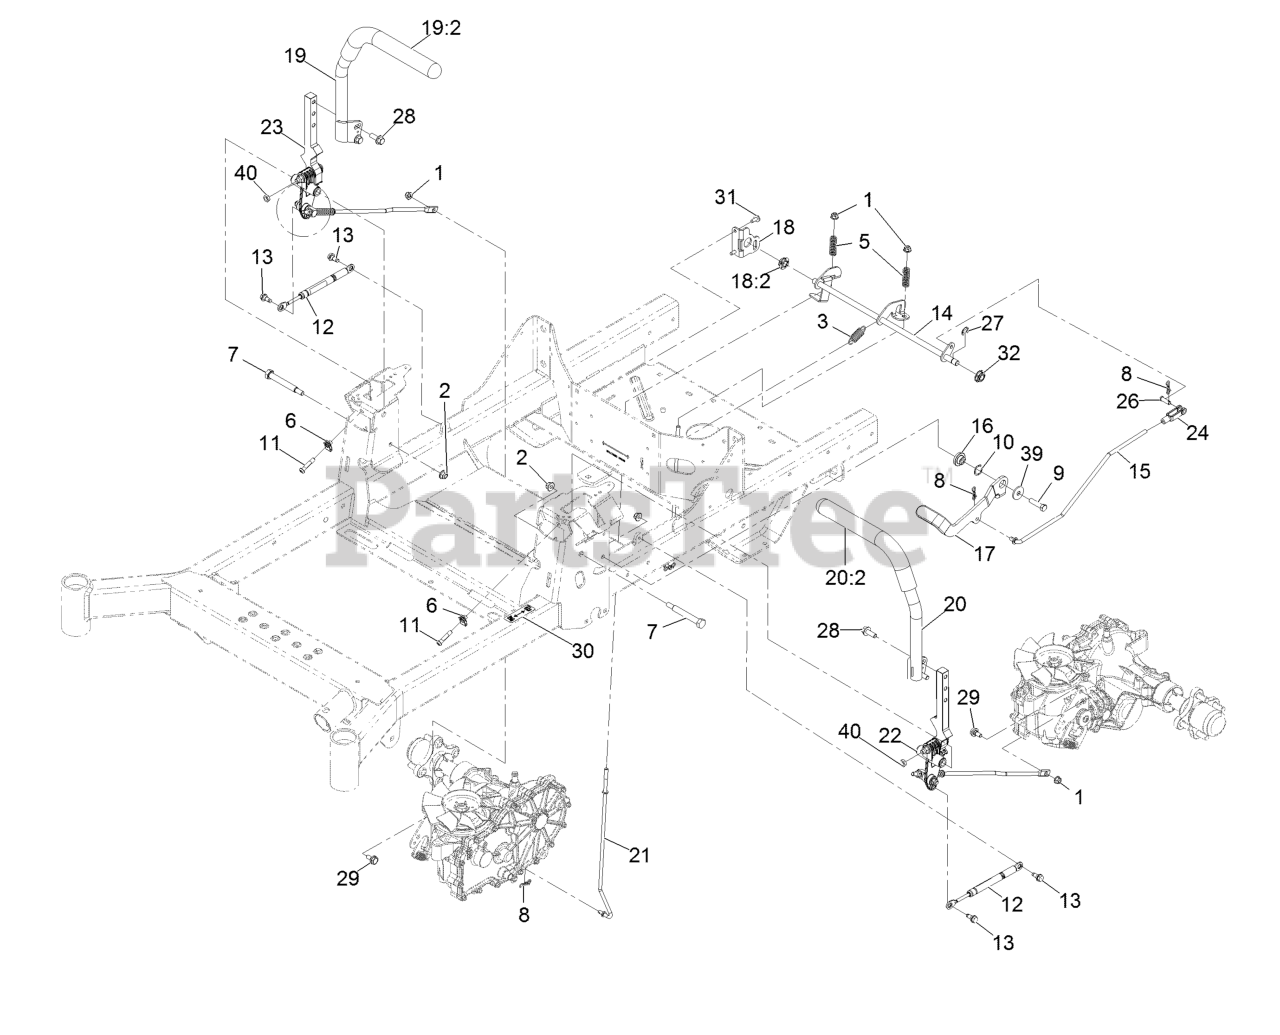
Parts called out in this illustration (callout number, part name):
1	Nut-Nyloc 5/16-18 Flg
2	Nut-Nyloc 3/8-16 Flg
3	Spring-Extension
5	Spring-Compression
7	Bolt-Pivot
8	Pin-Cotter, Locking
9	Screw-HH 3/8-16 X 1 1/2
10	Washer-Wave
11	Screw-HSBH
13	Screw-Shoulder
14	Shaft-Brake
15	Linkage-Brake, Upper
16	Pivot-Flange
17	Lever-Brake (With Grip)
18	Bracket-Brake
18:2	Bearing-Spherical
19	RH Control Handle ASM
20	LH Control Handle ASM
21	Linkage-Brake, Lower
24	Yoke-Adjustable
26	Pin-Clevis 5/16 X 1 49/64
27	Ring-Retaining
28	Screw HHF 3/8-16 X 1
29	Screw-Shoulder 5/16-18 X 5/8
30	Decal-Brake, Parking
31	Screw-1/4-20 X .65 Torx Plus
32	Bearing-Spherical
39	Washer
40	Nut-Jam 3/8-16
